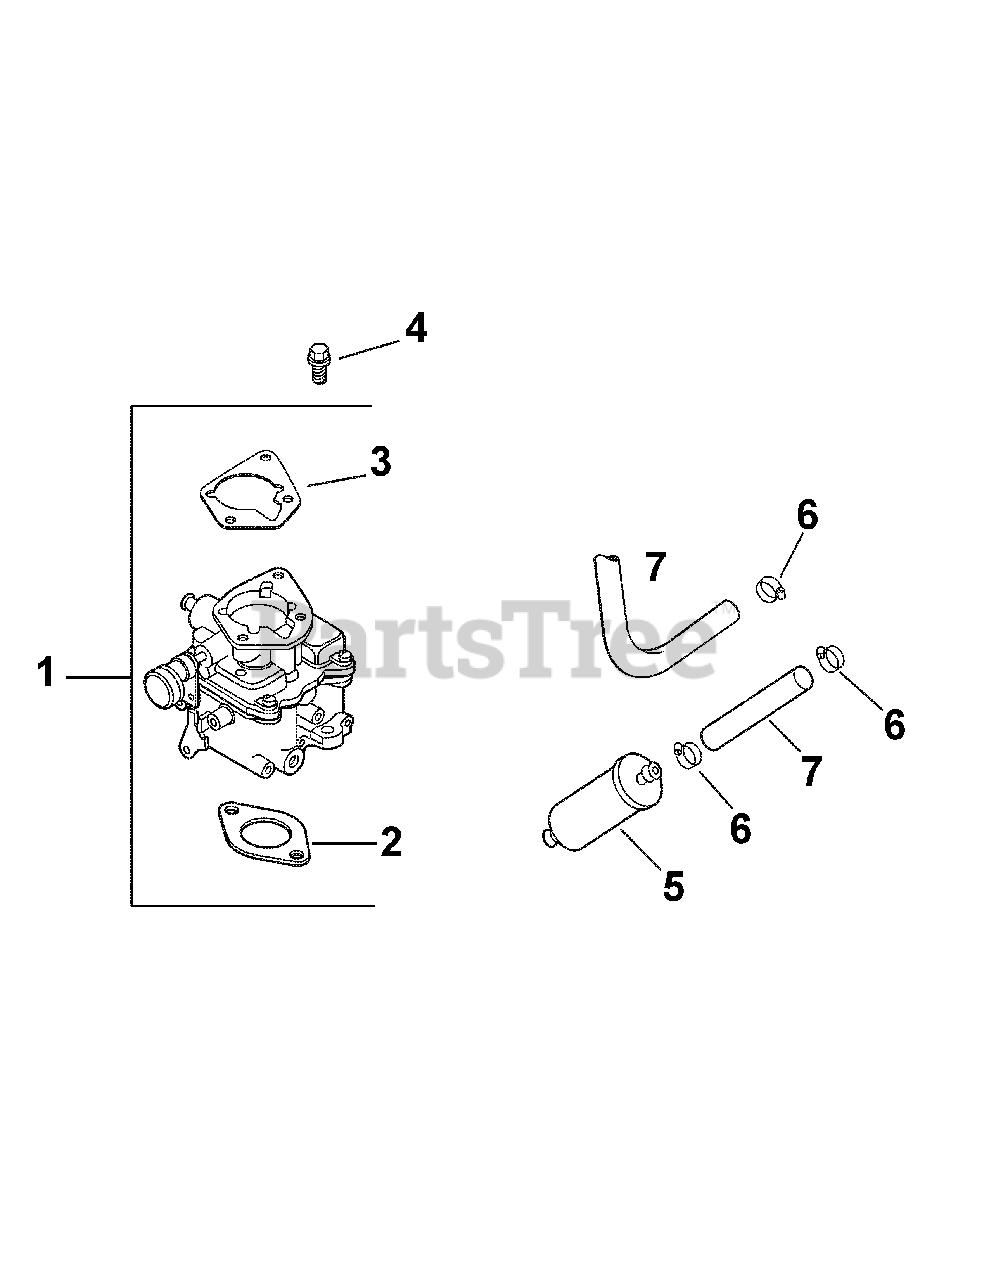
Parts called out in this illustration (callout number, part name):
1	Kit, carb w/gasket (Incl 2,3)
2	Gasket, air cleaner base
3	Gasket, carburetor
4	Screw, hex flange M6x1.0x25
5	Filter, fuel
6	Clamp, hose
7	Line, fuel 24" - cut to length
